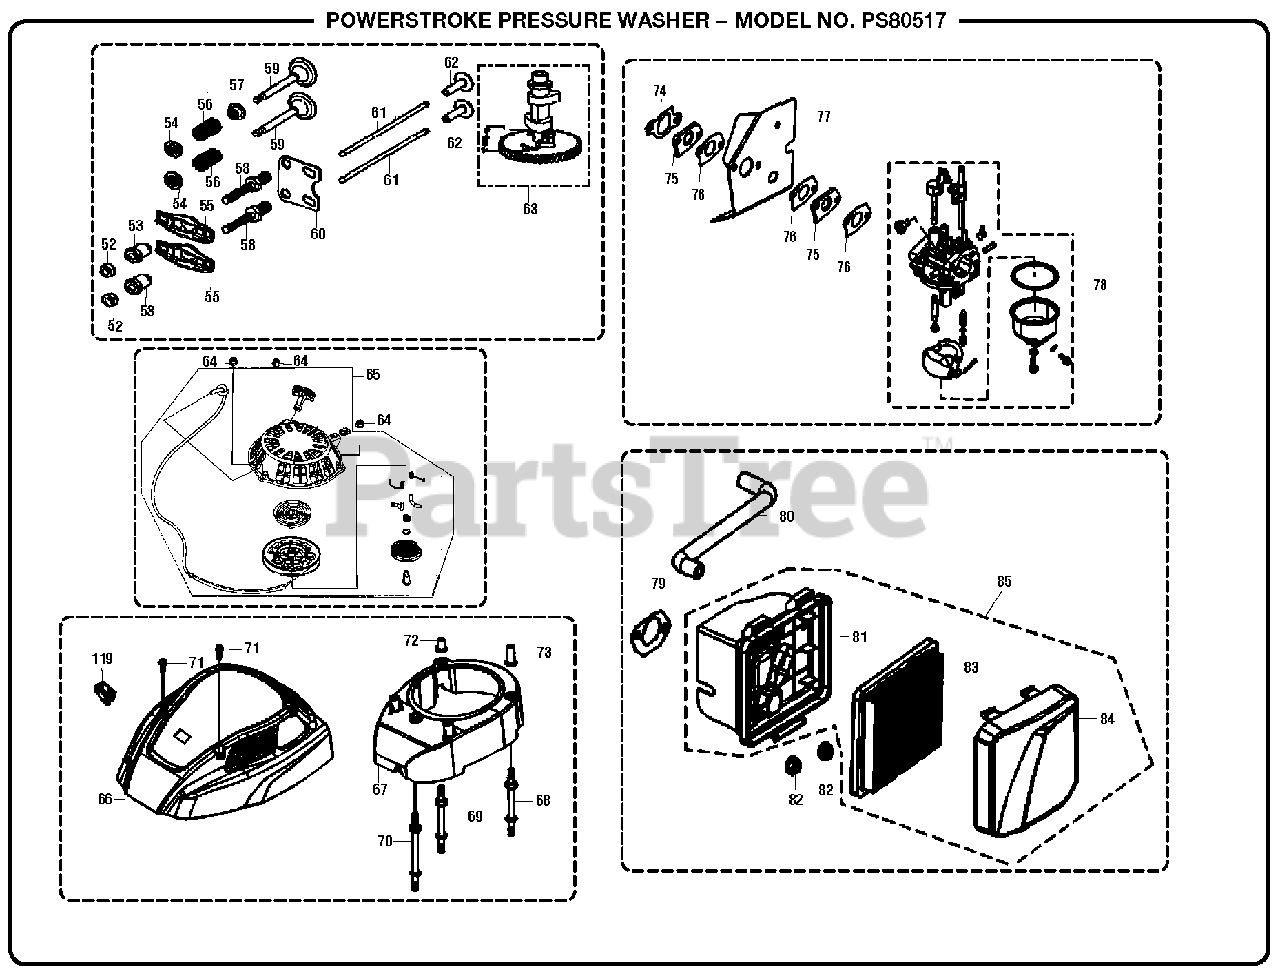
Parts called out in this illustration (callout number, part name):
52	Valve Lock Nut
53	Valve Adjusting Nut
54	Valve Spring Seat
55	Valve Rocker
56	Valve Spring
58	Valve Adjusting Bolt
59	Intake Valve
60	Lifter Stop Plate Assembly
61	Valve Lifter
62	Valve Tappet
63	Camshaft Assembly
65	Recoil Starts Assembly
74	Insulator Plate Gasket
75	Carburetor Insulator Plate
76	Carburetor Gasket
77	Carburetor Insulator Gasket
78	Carburetor Assembly
79	Air Cleaner Gasket
80	Breather tube
81	Air Cleaner Case
83	Air Cleaner Subassembly Element
84	Cleaner Case Cover
119	Stop Engine Switch
